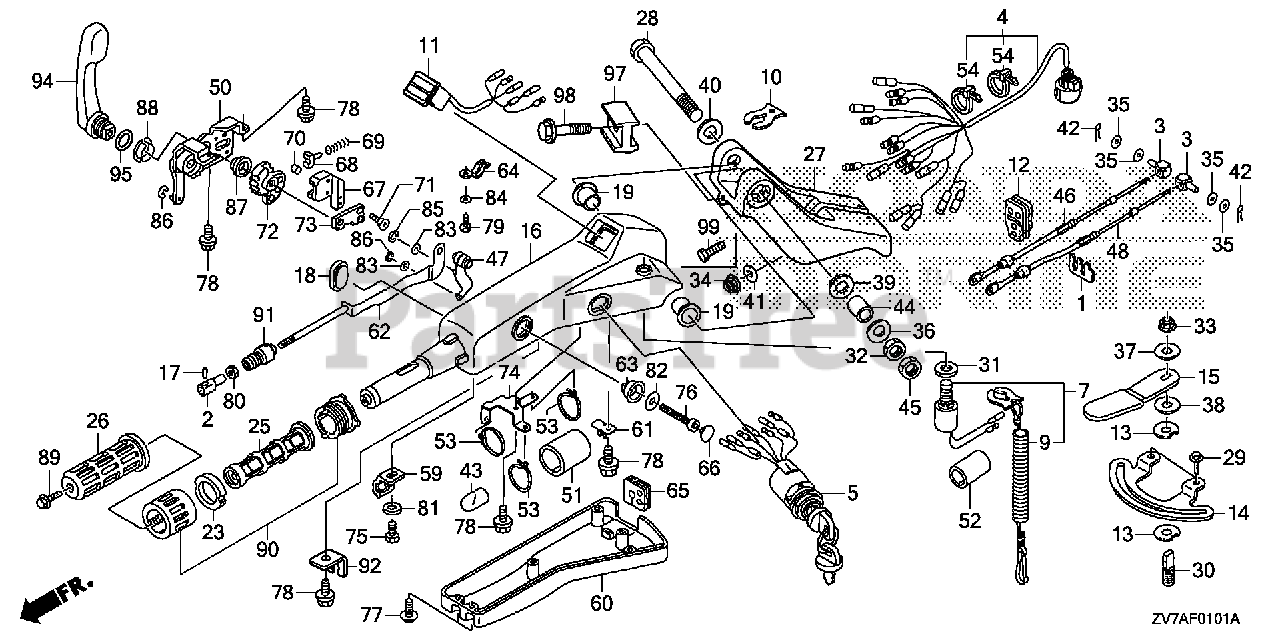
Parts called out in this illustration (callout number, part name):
1	PLATE, REMOTE CONTROL CABLE
2	PIVOT, THROTTLE CABLE
3	PIVOT, SHIFT
4	CABLE ASSY., LONG HANDLE (A)
5	SWITCH ASSY., COMBINATION
7	SWITCH ASSY., EMERGENCY STOP
9	WIRE, EMERGENCY
10	CLIP, EMERGENCY LOCK
11	LAMP ASSY., INDICATION (2-LED)
12	GROMMET, CASE (LOWER) (A)
13	BLOCK, FRICTION
14	PLATE, FRICTION
15	LEVER, FRICTION
16	HOUSING *NHB14M* (AQUA MARINE SILVER METALLIC)
17	PIN, THROTTLE CABLE
18	GROMMET, POWER TILT SWITCH
19	BUSH, HANDLEBAR
23	PAD, THROTTLE FRICTION
25	PIPE, GRIP
26	RUBBER, GRIP
27	BRACKET, STEERING *NHB14M* (AQUA MARINE SILVER METALLIC)
28	BOLT, HEX. (12X80)
29	BOLT, FLANGE (6X12)
30	BOLT, STUD (8X26)
31	NUT, HEX. (16MM)
32	NUT, HEX. (12MM)
33	NUT, SELF-LOCK (8MM)
34	NUT, SELF-LOCK (10MM)
35	WASHER, PLAIN (6MM)
36	WASHER, WAVE (14MM)
37	WASHER (8MM)
38	WASHER, NYLON (8MM)
39	WASHER, PLAIN (12MM)
40	WASHER, PLAIN (12MM)
41	WASHER, PLAIN (10MM)
41	WASHER (10MM)
42	PIN, SPECIAL LOCK (6MM)
43	TUBE, CORD (30MM)
44	COLLAR, DISTANCE (12.2X23X16)
45	NUT, HEX. (12MM)
46	CABLE, THROTTLE
47	ARM, THROTTLE
48	CABLE, SHIFT
50	FRAME ASSY., SHIFT
51	TUBE (38.1X40)
52	TUBE (19X40)
53	BAND (CONVEX CV-150)
54	BAND (CONVEX CV-200)
59	HOLDER, SWITCH
60	COVER, HANDLEBAR (LOWER)
61	BRACKET, CABLE
62	PLATE ASSY., LOCK
64	PLATE, GUIDE
67	GUIDE, SPRING
69	SPRING, COIL
71	SCREW (M5X14)
72	GEAR, SHIFT
73	PLATE, BALL GUIDE
75	BOLT (M5X8)
76	BOLT (M8X50)
77	BOLT (M5X12)
78	BOLT (M6X12)
79	BOLT (M5X12)
80	NUT, HEX. (5MM)
81	WASHER (5MM)
82	WASHER (8MM)
83	WASHER (10MM)
84	WASHER (5MM)
89	BOLT, FLANGE (6X12)
90	GRIP ASSY., THROTTLE FRICTION
91	ROD, GROMMET
92	CLAMP, BRACKET
94	LEVER, SHIFT
95	O-RING (20.6X1.9)
97	BLOCK, HEIGHT ADJUSTER
98	BOLT, FLANGE (8X28)
99	BOLT, HEX. (10X32)
